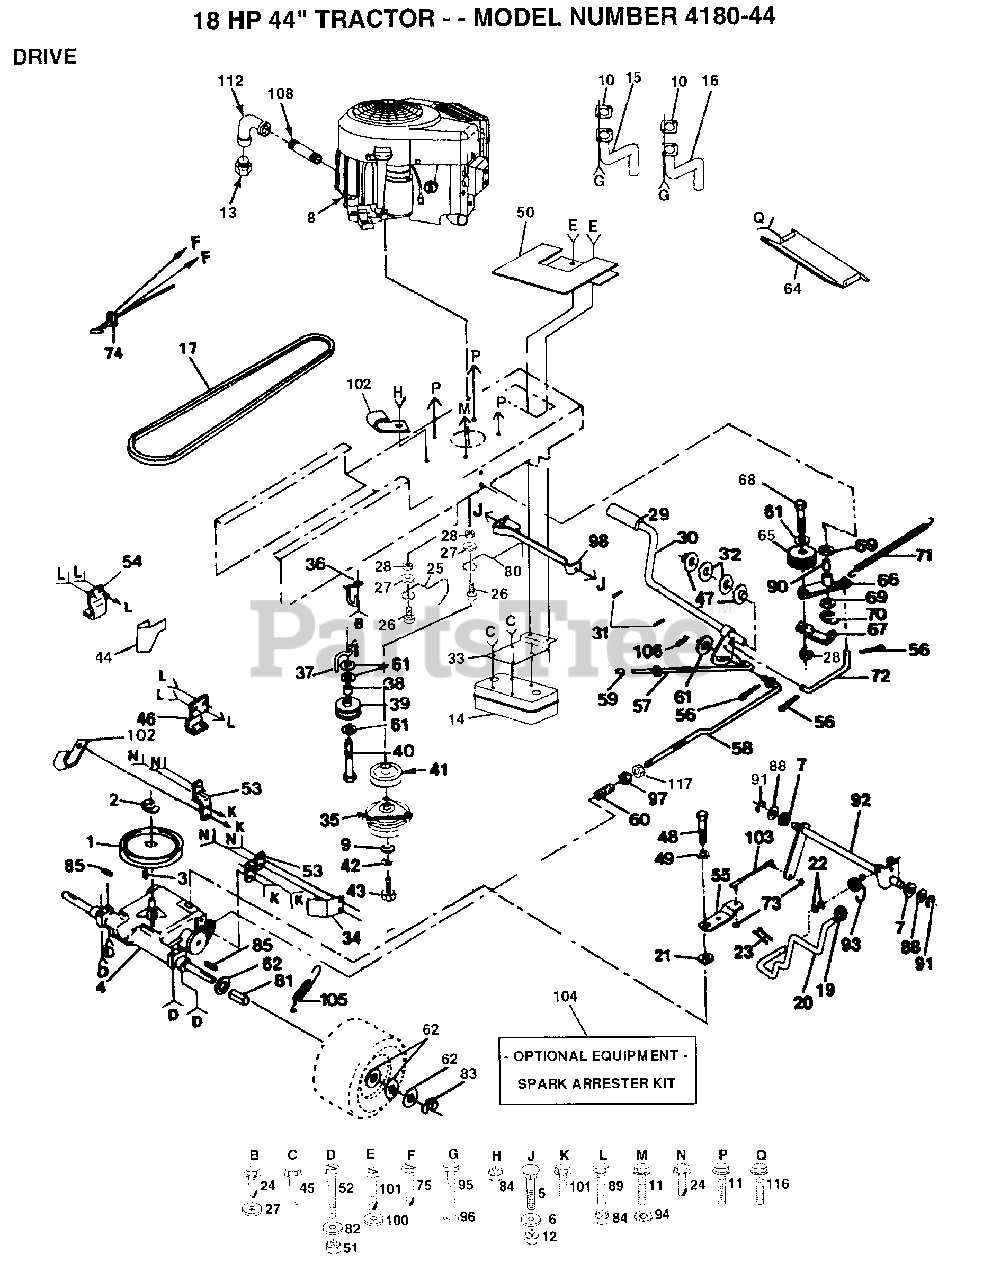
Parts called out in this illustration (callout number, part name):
1	PULLEY TRANSAXLE
2	RING
4	TRANSAX. PRLES.
5	BOLT
6	WASHER T
7	BUSHING
8	ENGINE, B&S
9	WASHER
11	SCREW LT
15	EXHAUST ASM LH
17	BELT.GRDRV.94.75
19	KNOB T (1/2-HOLE)
21	WASH-SHFT PLT LT
22	WASHER
23	PIN COTTER 1/8
24	SCREW
25	KEEPER BELT ENGLH
26	BOLT
27	WASHER
29	PEDAL COVER T
32	WASHER LT
33	BRACKET MUFFLER
34	"KEEPER,BELT RH"
36	KEEPER BELT CNTSP
37	BELT KEEPER LT
38	SPACER T
39	PULLEY.IDLER.FLAT
40	BOLT
41	PULLEY ENGINE
42	LOCKWASHER
44	KEEPER BELT LH
45	SCREW ST
46	BRKT TRANS RH
47	NYLON BEARING
48	BOLT, 1/4-28 X 3/4
49	WASHER PM
50	SHIELD HEAT LT
51	NUT
52	BOLT HEX
53	STRAP TORQUE
54	BRKT TRANS LH
55	"ARM,SHIFT"
56	COTTER PIN
57	BRAKE PARK ROD
58	ROD BRAKE
59	PLUNGER CAP T
60	"SPRING,ROD BRAKE"
61	WASHER
62	WASHER
64	HEAT SHIELD
66	ARM IDLER
67	RETAIN BELT
69	WASHER LT
70	KLIP RING
71	"SPRING, RETURN LT"
72	"LINK, CLUTCH T"
73	NUT 1/4-28
75	SCREW LT
80	"KEEPER,BLT ENG LT"
81	SPACER HYT
82	WASHER M
83	E RING HYT
84	NUT
85	SQ KEY STD
88	WASHER D
90	"LY, BEARING"
91	KLIP RING
92	"SHAFT,SHIFTER"
93	"SPRING,TORSION"
94	LOCKWASHER
96	LOCKWASHER
97	NUT
98	BRACKET.ASM.MTG
100	WASHER
101	SCREW
102	CLIP T
103	"ROD,TIE "
106	RETAINER M
108	PIPE NIPPLE LT
112	ELBOW
116	SCREW
117	NUT
